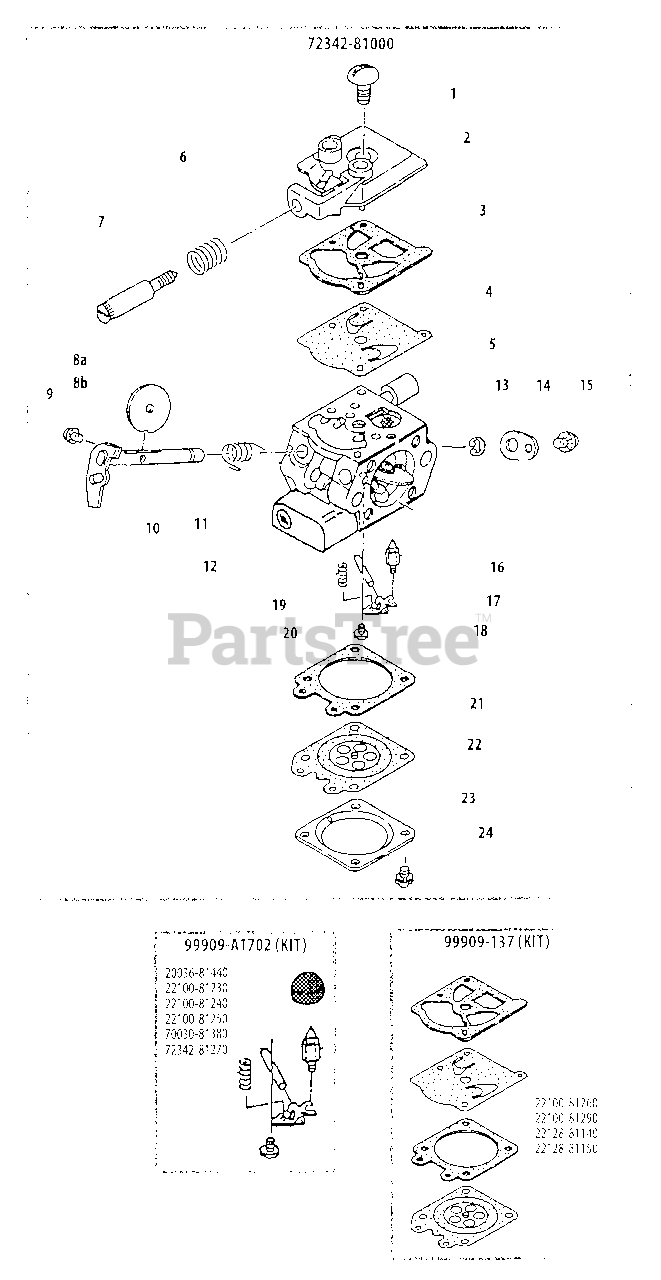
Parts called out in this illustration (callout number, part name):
1	SCREW
2	COVER ASSY, PUMP
3	GASKET, PUMP
4	DIAPHRAGM, PUMP
5	SCREEN, FUEL INLET
6	SPRING, IDLE ADJUST
7	SCREW, IDLE ADJUST
8A	VALVE, THROTTLE
8B	VALVE, THROTTLE
9	SCREW ASSY
10	SHAFT, THROTTLE
11	SPRING, THROTTLE RETURN
12	LIMITER CAP, L SPEED
13	E-RING
14	LEVER, THROTTLE
15	SCREW
16	VALVE, INLET NEEDLE
17	PIN, METERING LEVER
18	LEVER, METERING
19	SPRING, METERING LEVER
20	SCREW, METERING LEVER PIN
21	GASKET, METERING DIAPHRAGM
22	DIAPHRAGM, METERING
23	COVER, METERING DIAPHRAGM
24	SCREW
72342-81000	CARBURETOR
99909-137	DIAPHRAGM/GASKET KIT
99909-A1702	REPAIR KIT
